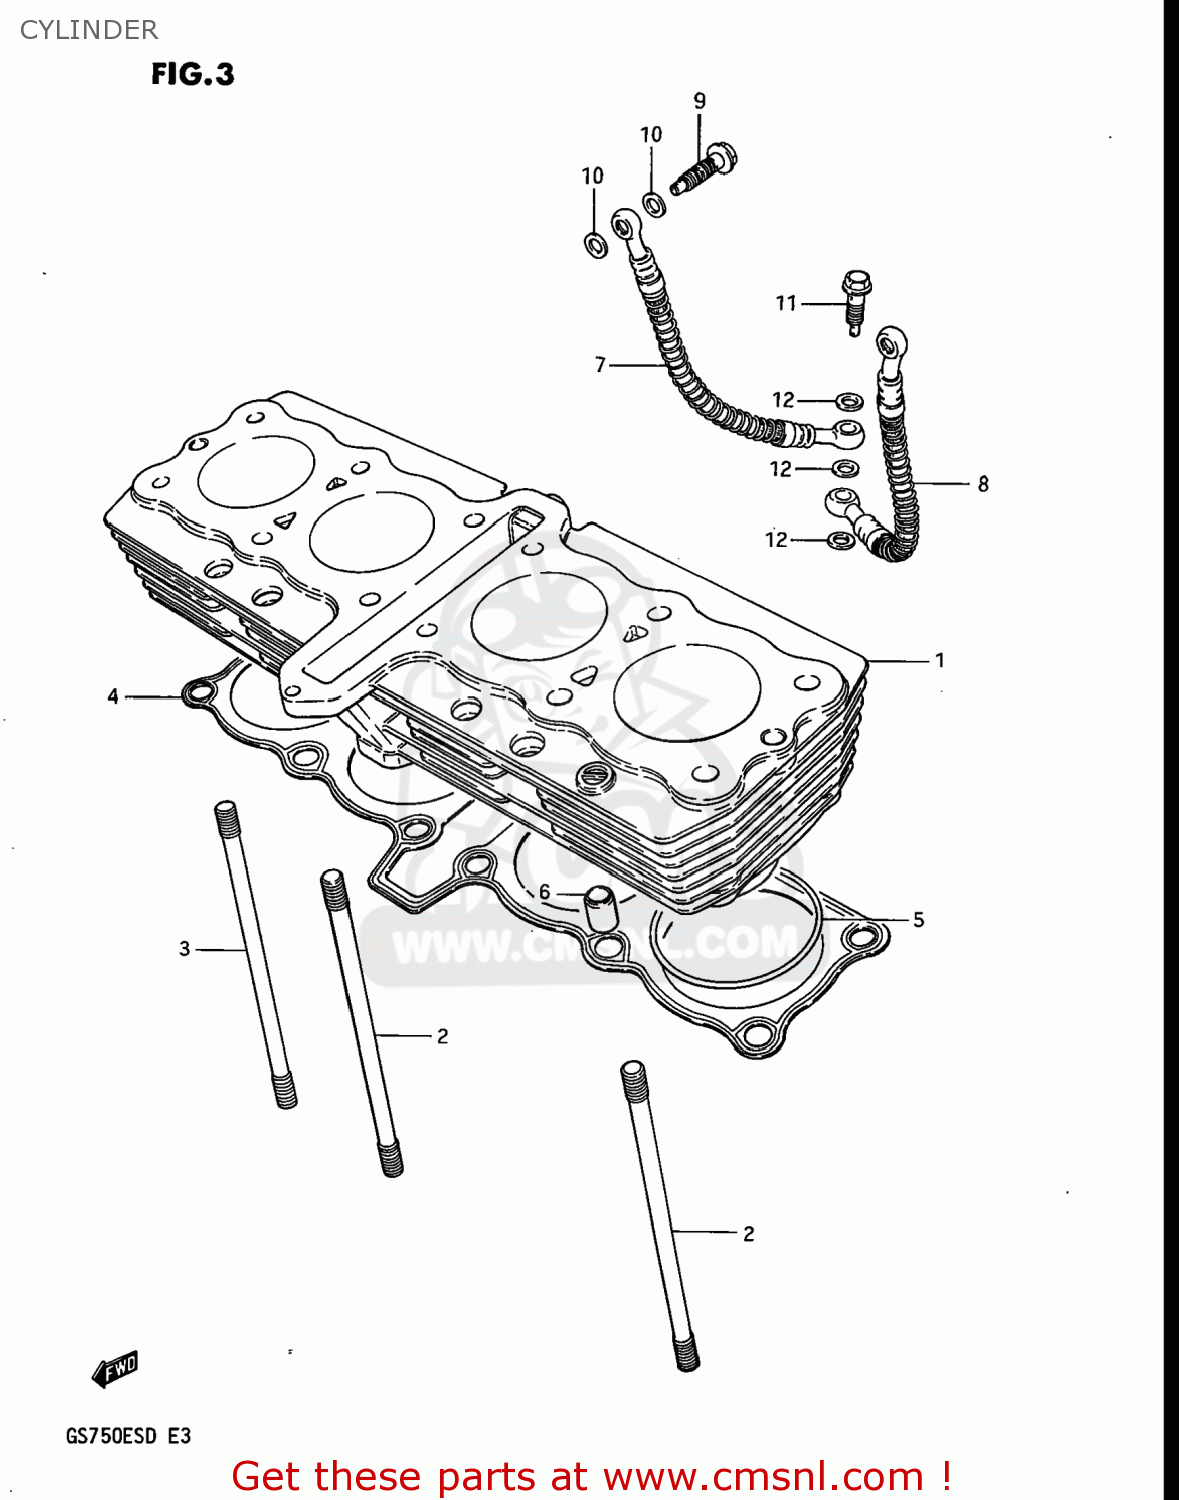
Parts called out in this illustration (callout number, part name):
1	CYLINDER
2	STUD
3	STUD
4	GASKET,CYLINDER
5	O RING(D:2,ID:70)
6	PIN
7	HOSE,OIL
8	HOSE,OIL
9	BOLT UNION
10	GASKET 8.2X14X1 (NAS)
11	BOLT,OIL PIPE
12	WASHER
